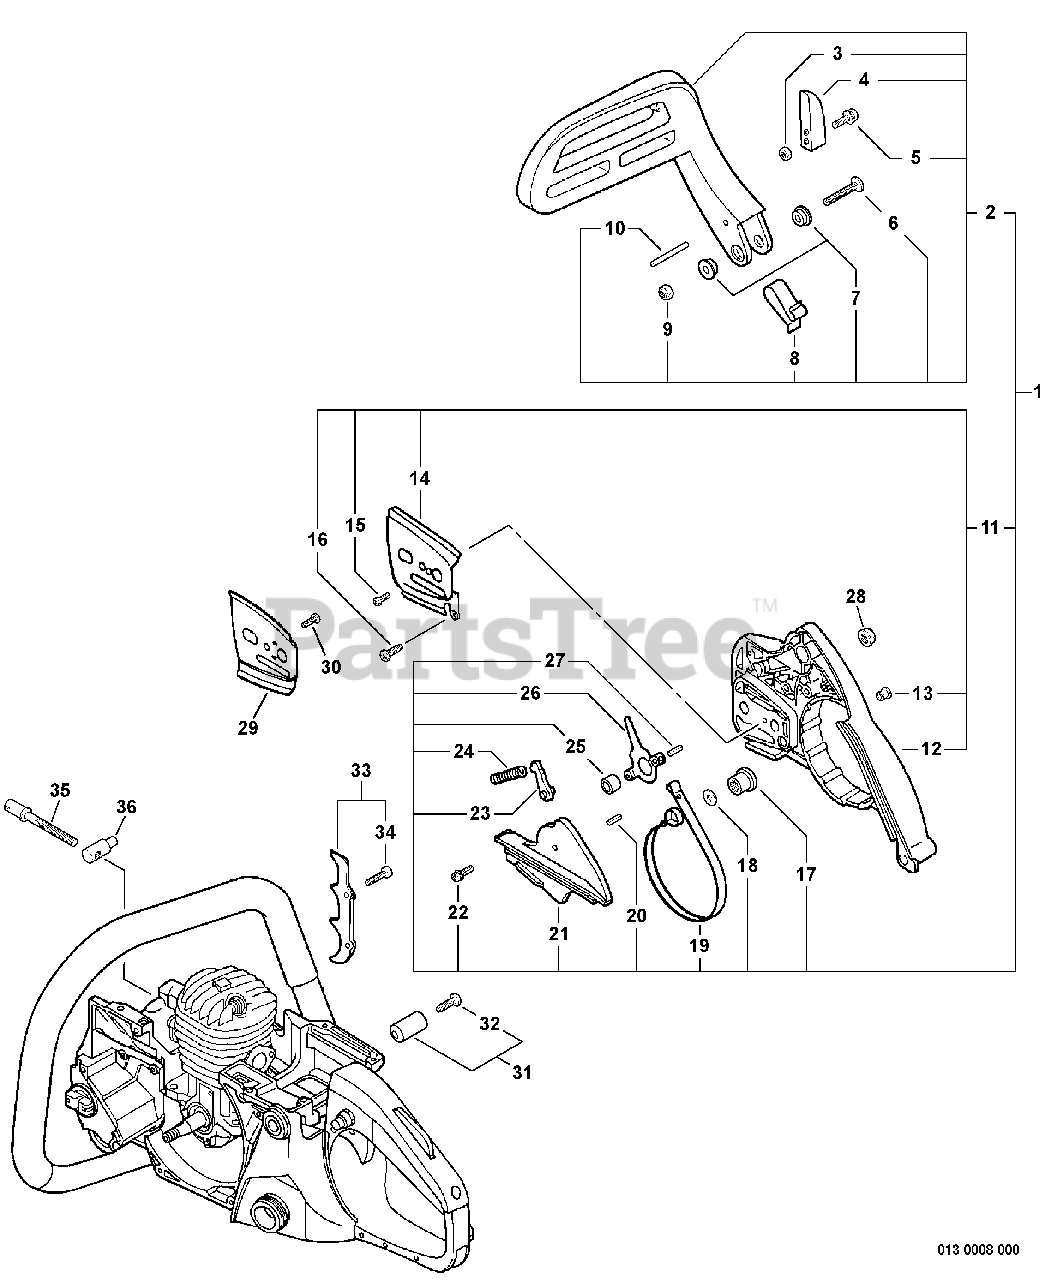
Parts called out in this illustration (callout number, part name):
1	CHAIN BRAKE ASSY
2	BRAKE LEVER ASSY
4	WEIGHT, BRAKE
5	SCREW - 4X18
6	SCREW - 5X32
9	LOCKNUT - 5
10	PIN - 3X24
11	SPROCKET GUARD ASSY
12	GUARD, SPROCKET
14	PLATE, GUIDE - OUTER
15	SCREW - 3X6
16	SCREW - 4X10
17	ADJUSTER, BRAKE BAND
18	WASHER - 8
19	BAND, BRAKE
20	PIN - SPRING -- 2.5X12
21	COVER, BRAKE
22	SCREW - 4X10
23	STOPPER, BRAKE
24	SPRING, BRAKE
25	WASHER - 5
26	LEVER, BRAKE
27	PIN - SPRING -- 4X8
28	NUT - FLANGE
29	PLATE, GUIDE - INNER
30	SCREW - 4X6
31	CHAIN CATCHER KIT
32	SCREW - 5X18
33	SPIKE KIT
34	SCREW - 5X12
35	SCREW, TENSIONER
36	TENSIONER, CHAIN
